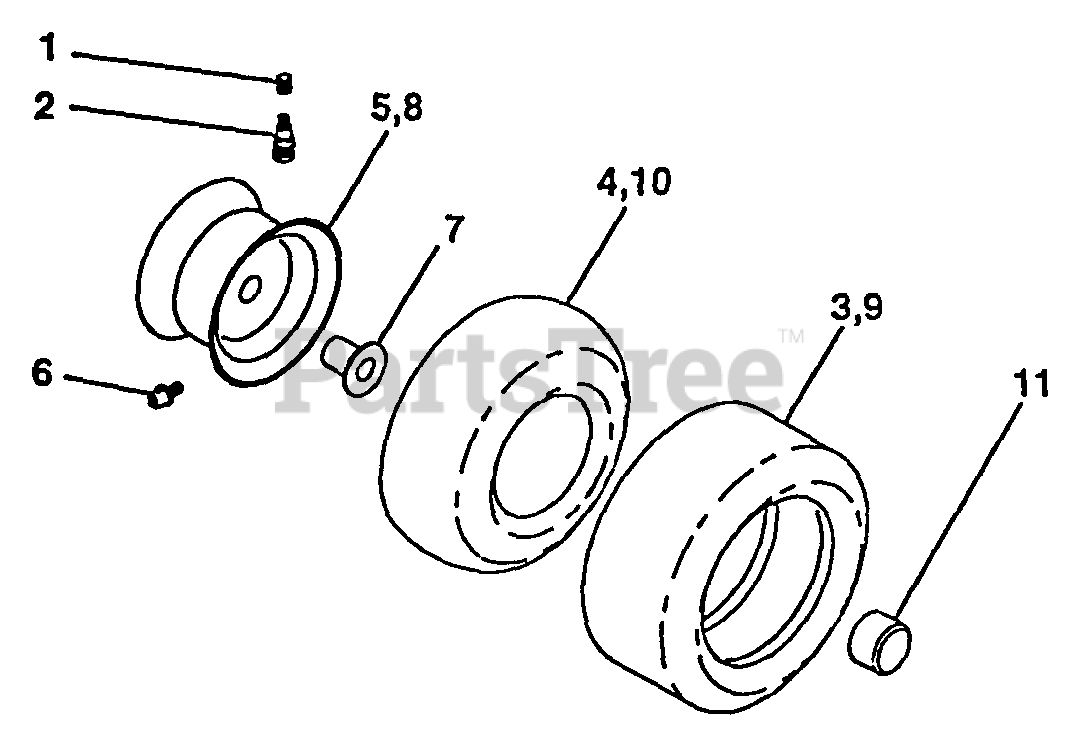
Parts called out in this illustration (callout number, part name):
1	Cap Valve Tire
2	Stem Valve
3	Tire F Ts 15 X 6 0 - 6 Service
4	Tube Front
5	Rim Asm 6" front Silver Service
6	Fitting Grease
7	Bearing Flange
8	Rim Asm 8" rear Silver Service
9	Tire R Ts 20x10 -8 C Service
10	Tube Rear
11	Cap Axle Blk 1 50 X 1 00
